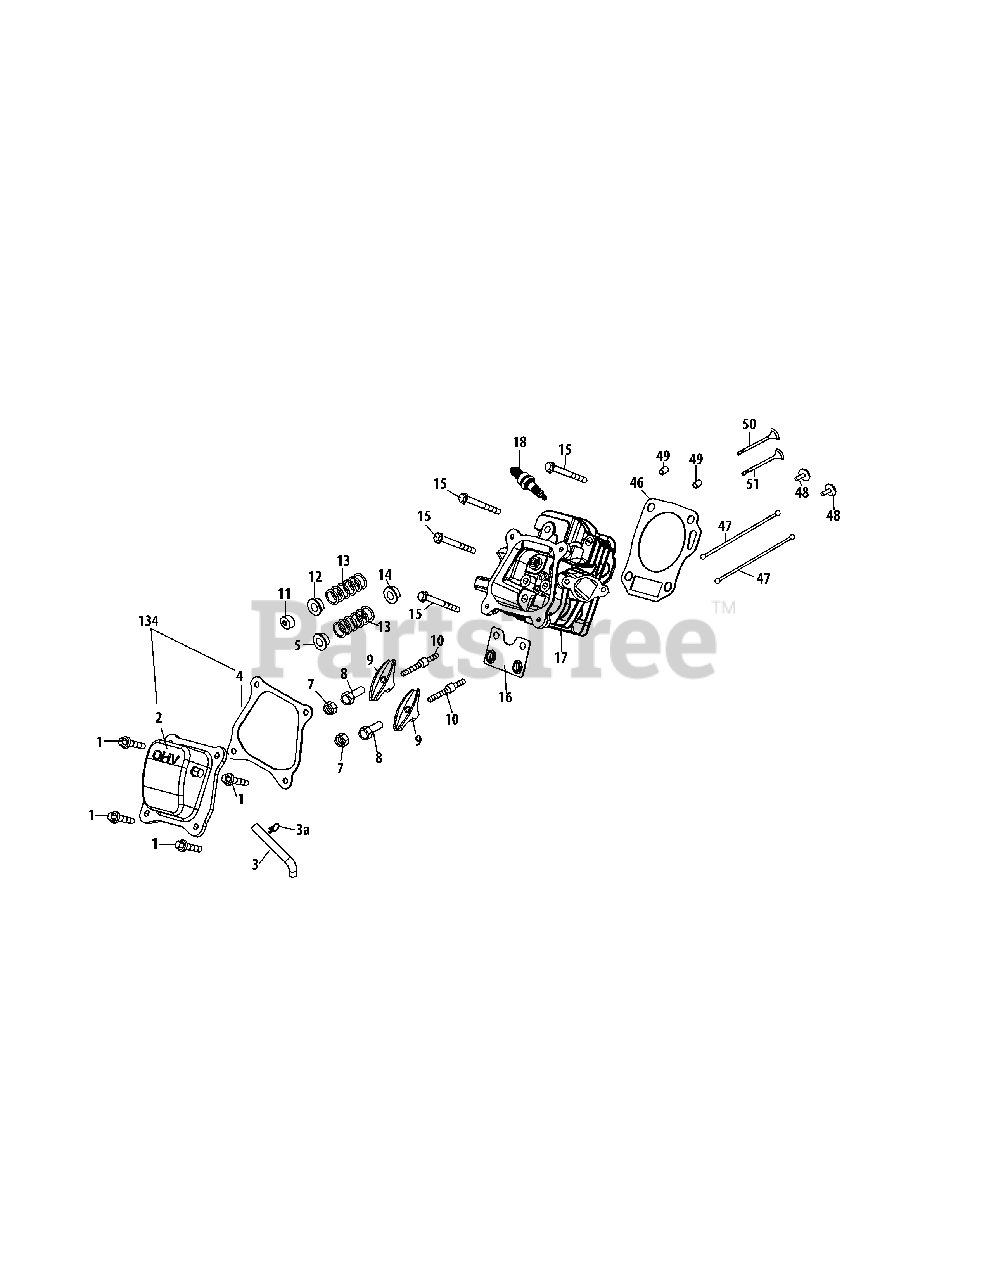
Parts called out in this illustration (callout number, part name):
1	Bolt M6×16
2	Valve Cover
3	Breather Hose
4	Valve Cover Gasket
5	Retainer, Intake Valve Spring
7	Nut, Pivot Locking
8	Adjusting Nut, Valve
9	Rocker Arm
10	Bolt, Pivot
11	Adjuster, Exh Valve
12	Retainer, Exhaust Valve Spring
13	Valve Spring
14	Intake Valve Seal
15	Bolt M8×55
16	Push Rod Guide
17	Cylinder Head Assembly
18	Spark Plug/F6Rtc
46	Gasket, Cylinder Head
47	Push Rod Kit ( Qty 2 )
49	Dowel Pin 10×16
50	Valve Kit
51	Valve Kit
134	Valve Cover Kit
